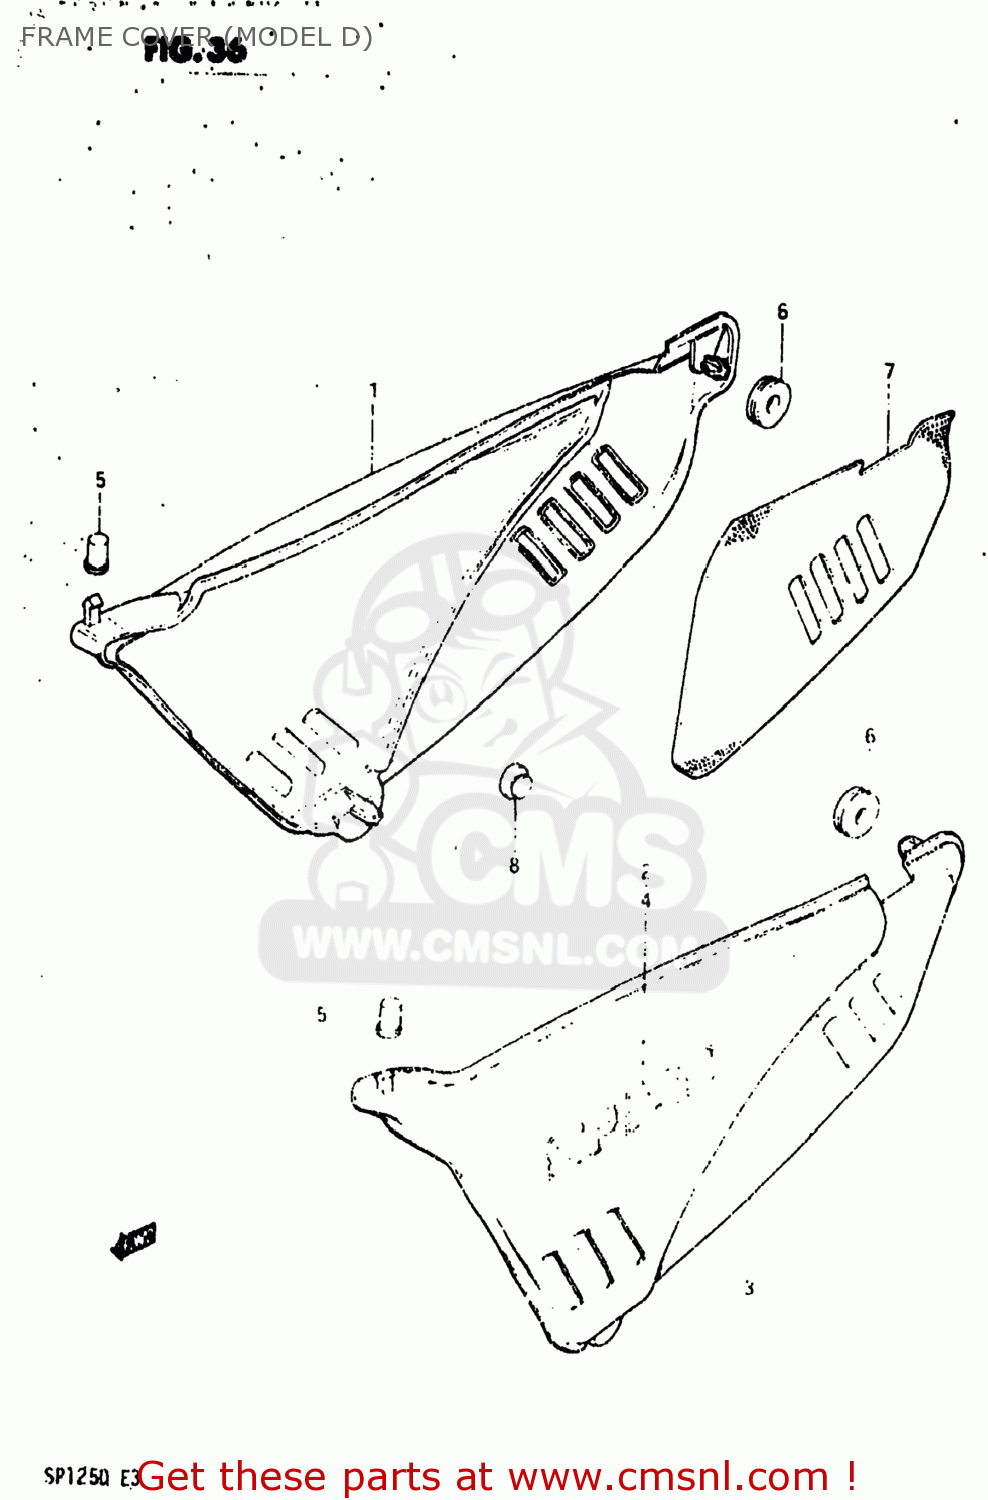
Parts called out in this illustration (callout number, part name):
1	COVER,FRAME,RIGHT
2	EMBLEM
3	COVER,FRAME,LEFT
4	EMBLEM
5	CUSHION
6	CUSHION
7	HEAT SHIELD,FRAME COVER
8	CUSHION
